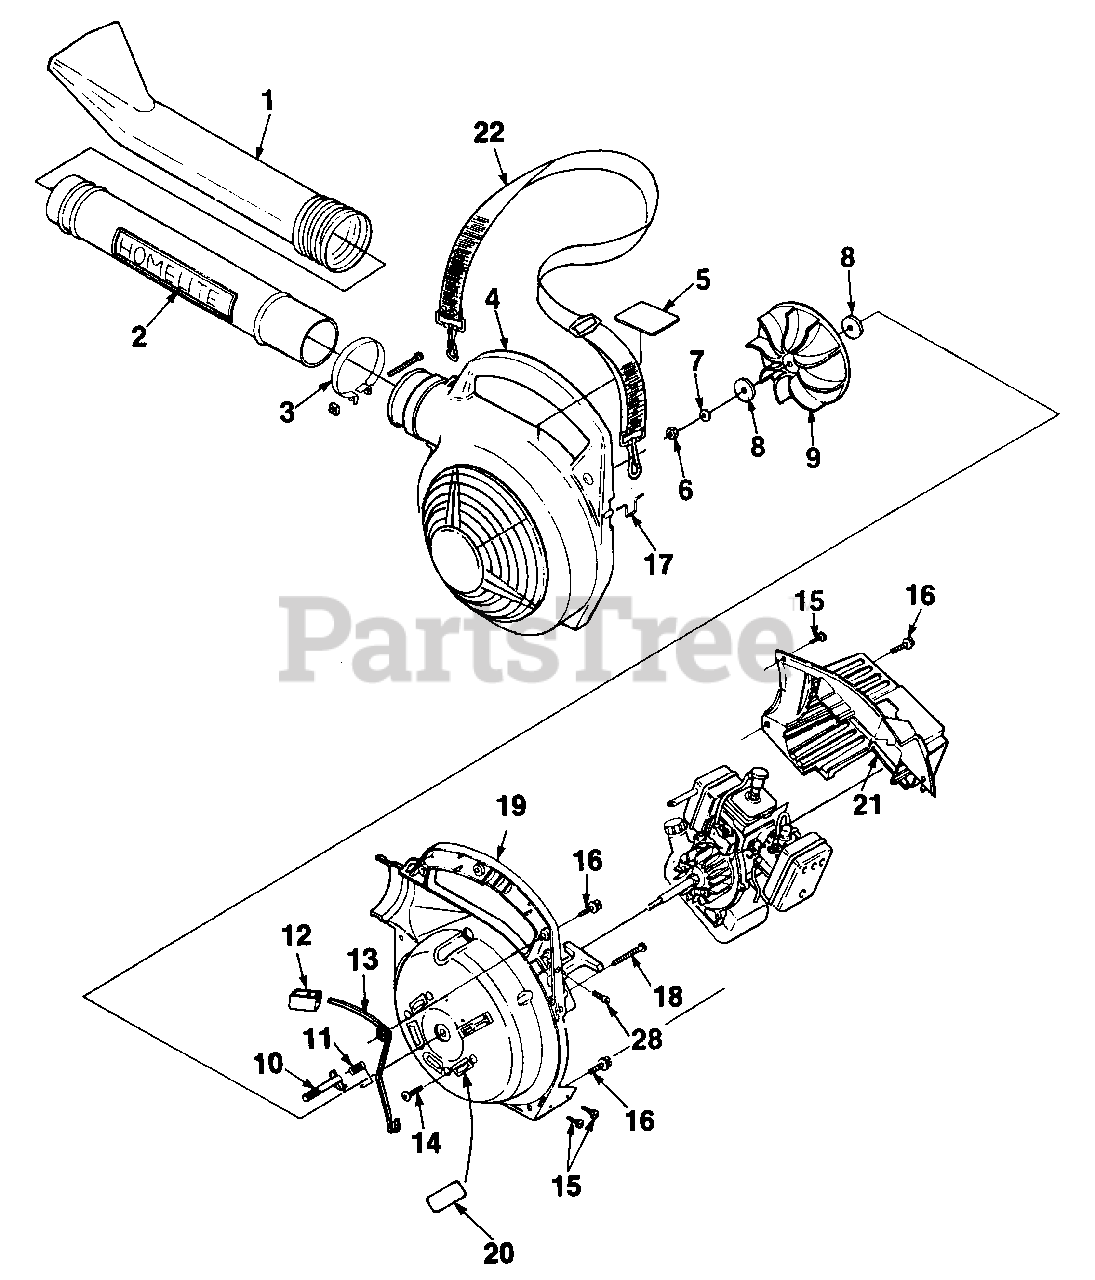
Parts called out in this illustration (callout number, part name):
1	NOZZLE - Sweeper
2	TUBE w/DECAL
3	CLAMP
4	HOUSING - Volute (outer)
5	DECAL - Warning
6	NUT - Hex 5/16-24
7	WASHER - Belleville #10
8	WASHER - Flat
9	FAN - Blower
10	LATCH - Throttle
11	SPRING - Throttle latch
12	TRIGGER - Throttle
13	LEVER - Throttle
14	SCREW - Thd Forming
15	SCREW - Tapping pan #8 x 1/2
16	SCREW - Thd forming #10 x 3/4
17	LOOP - Wire
18	SCREW - Hex hd. #10 x 1 5/8
19	HOUSING - Volute (inner)
20	KIT - Sealing
21	SHROUD
22	STRAP - Shoulder (Acc.)
